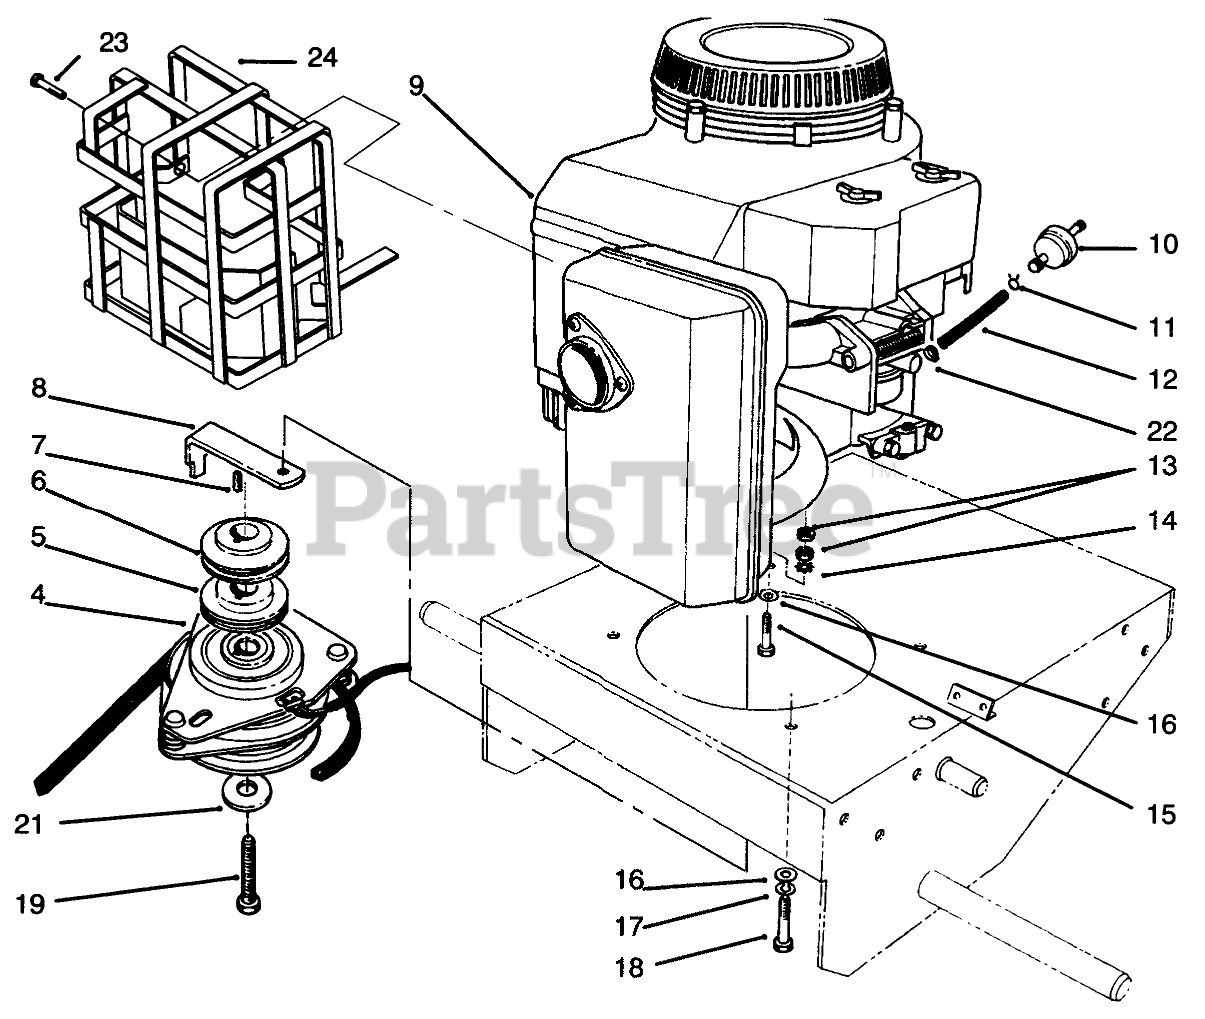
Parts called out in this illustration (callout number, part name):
4	CLUTCH/BRAKE
5	SHEAVE-LOWER HALF
6	SHEAVE-UPPER HALF
8	Retainer-Clutch
10	FILTER-FUEL
11	CLAMP-HOSE
12	HOSE-FUEL
13	NUT-JAM
14	WASHER-LOCK
15	SCREW (ENGINE, GROUND)
16	WASHER-PLAIN
17	WASHER-LOCK
18	SCREW-HH
19	SCREW-CLUTCH
21	WASHER
22	CLAMP-WORM
23	Screw-Hex. Hd. (Engine)
24	Guard-Muffler
